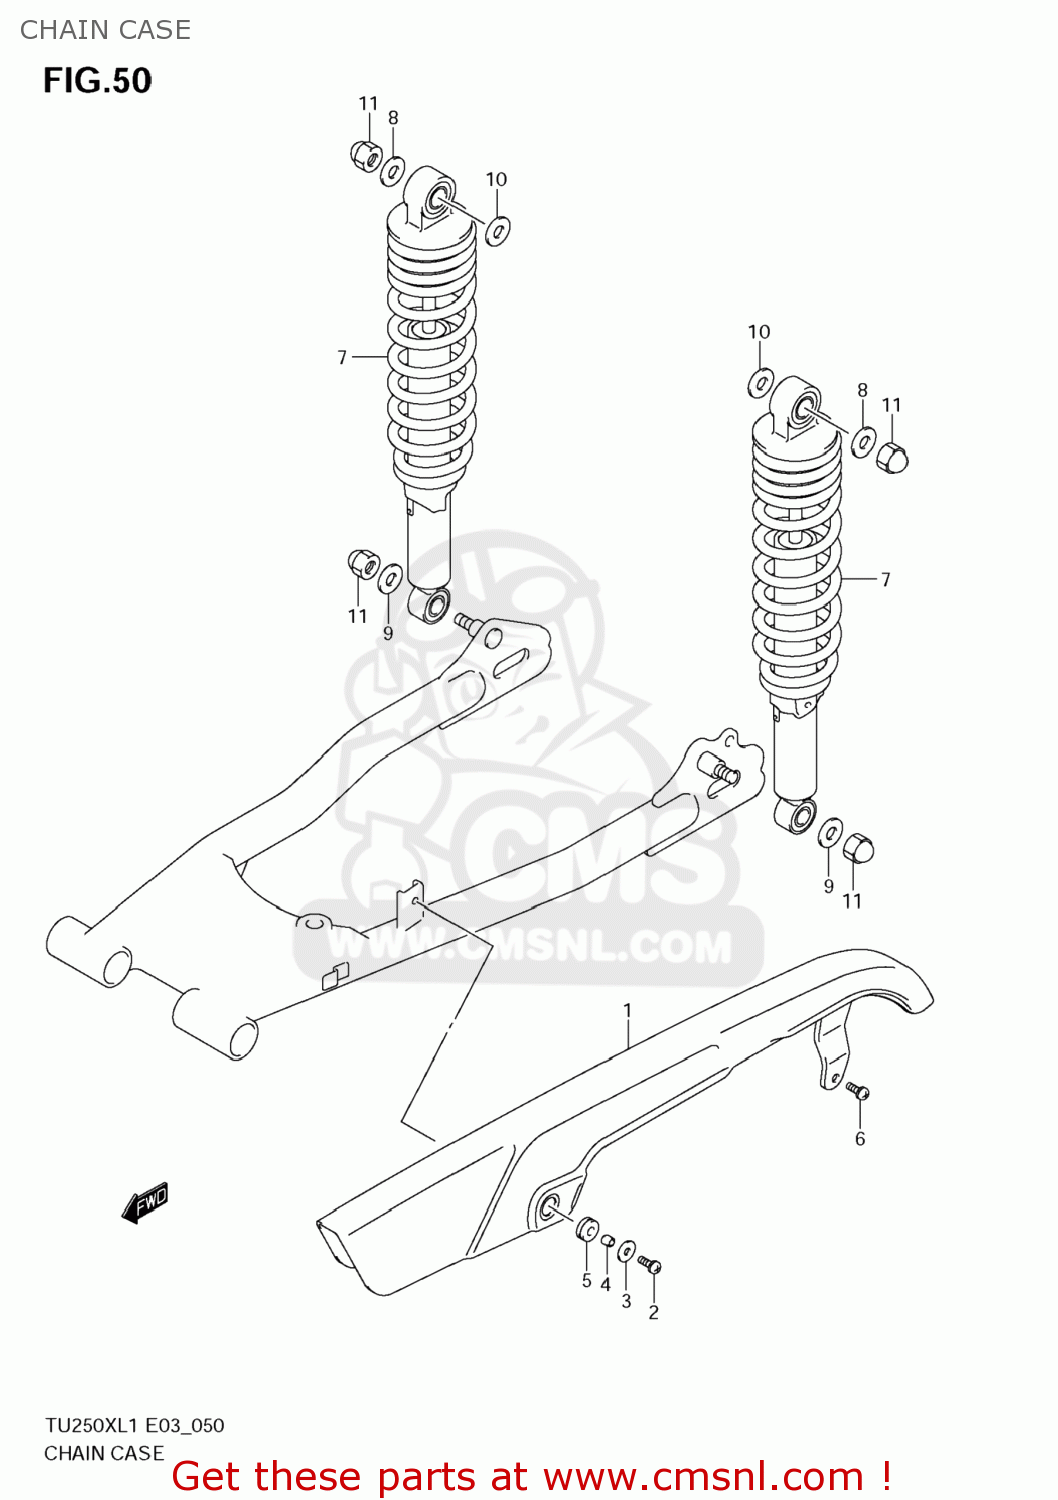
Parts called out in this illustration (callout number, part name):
1	CASE,CHAIN
2	SCREW
3	WASHER(6.5X20X1.2)
4	WASHER
5	CUSHION
6	SCREW
7	ABSORBER ASSY,RR SHOCK
8	WASHER(10.5X24X2.3)
9	WASHER(10.5X24X2.3)
10	WASHER(12.5X24X3.2)
11	NUT
